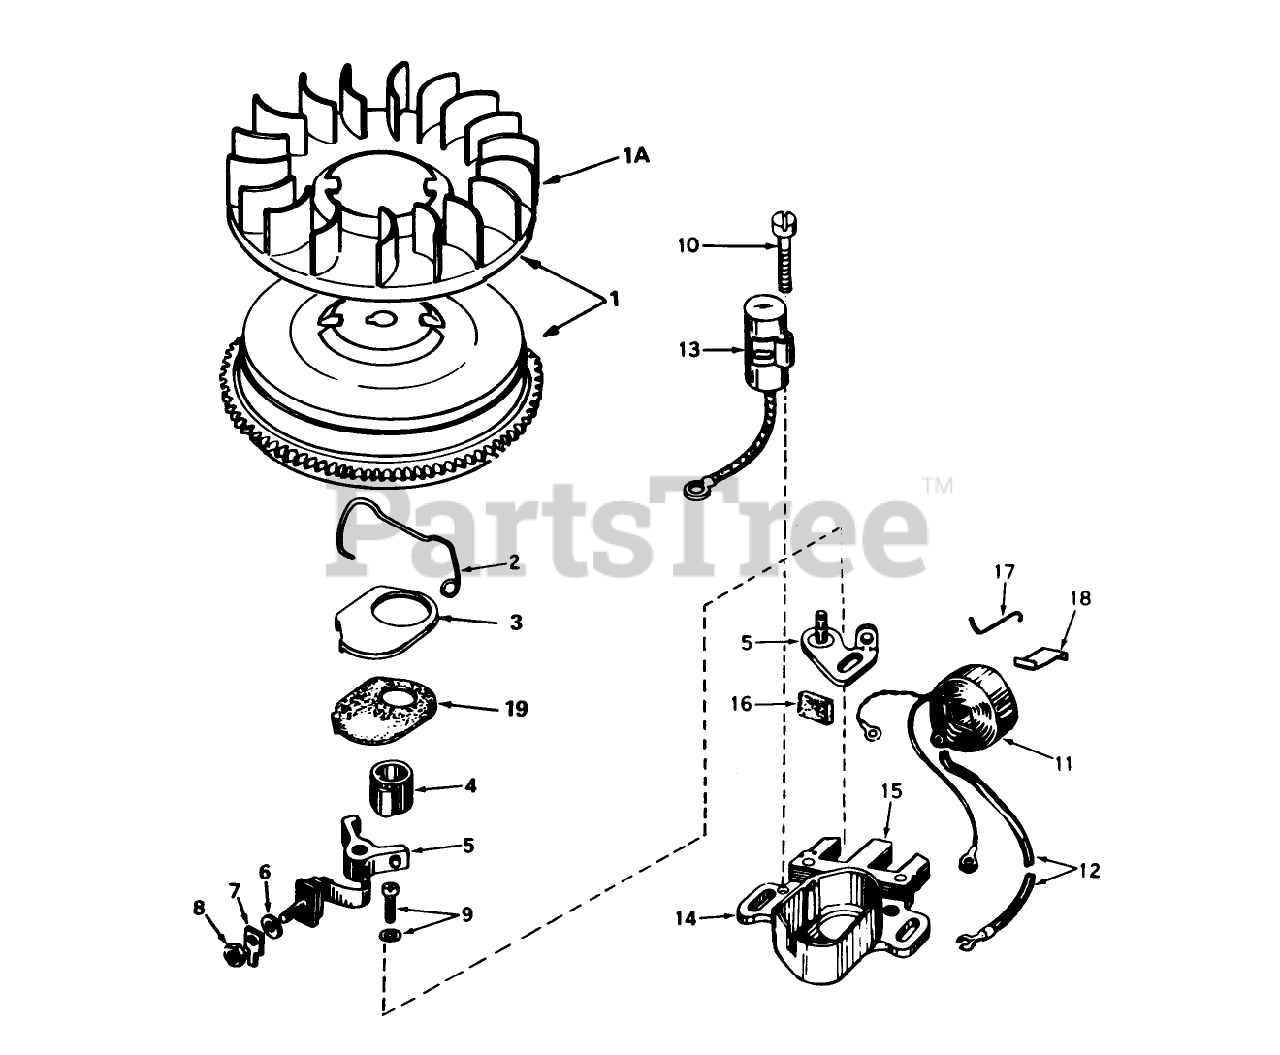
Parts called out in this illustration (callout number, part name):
1	A Flywheel (Incl. Ref. #1A)
2	Spring Breaker Box
3	Cover-Dust
4	Cam-Breaker
5	Breaker Assy.
7	Terminal, Ground
9	Breaker Screw
10	Condenser Screw
11	Coil Assy. (Incl. Ref. #12)
12	Wire, Lead
13	Condenser
14	Core & Plate
15	Stator Assy. (Incl. Ref. #2, 3, 5thru 14 & 16 thru 19)
16	Felt,Cam Wiper
17	Clip, Coil
18	Spring Coil Wedge
19	Gasket-Dust Cover
